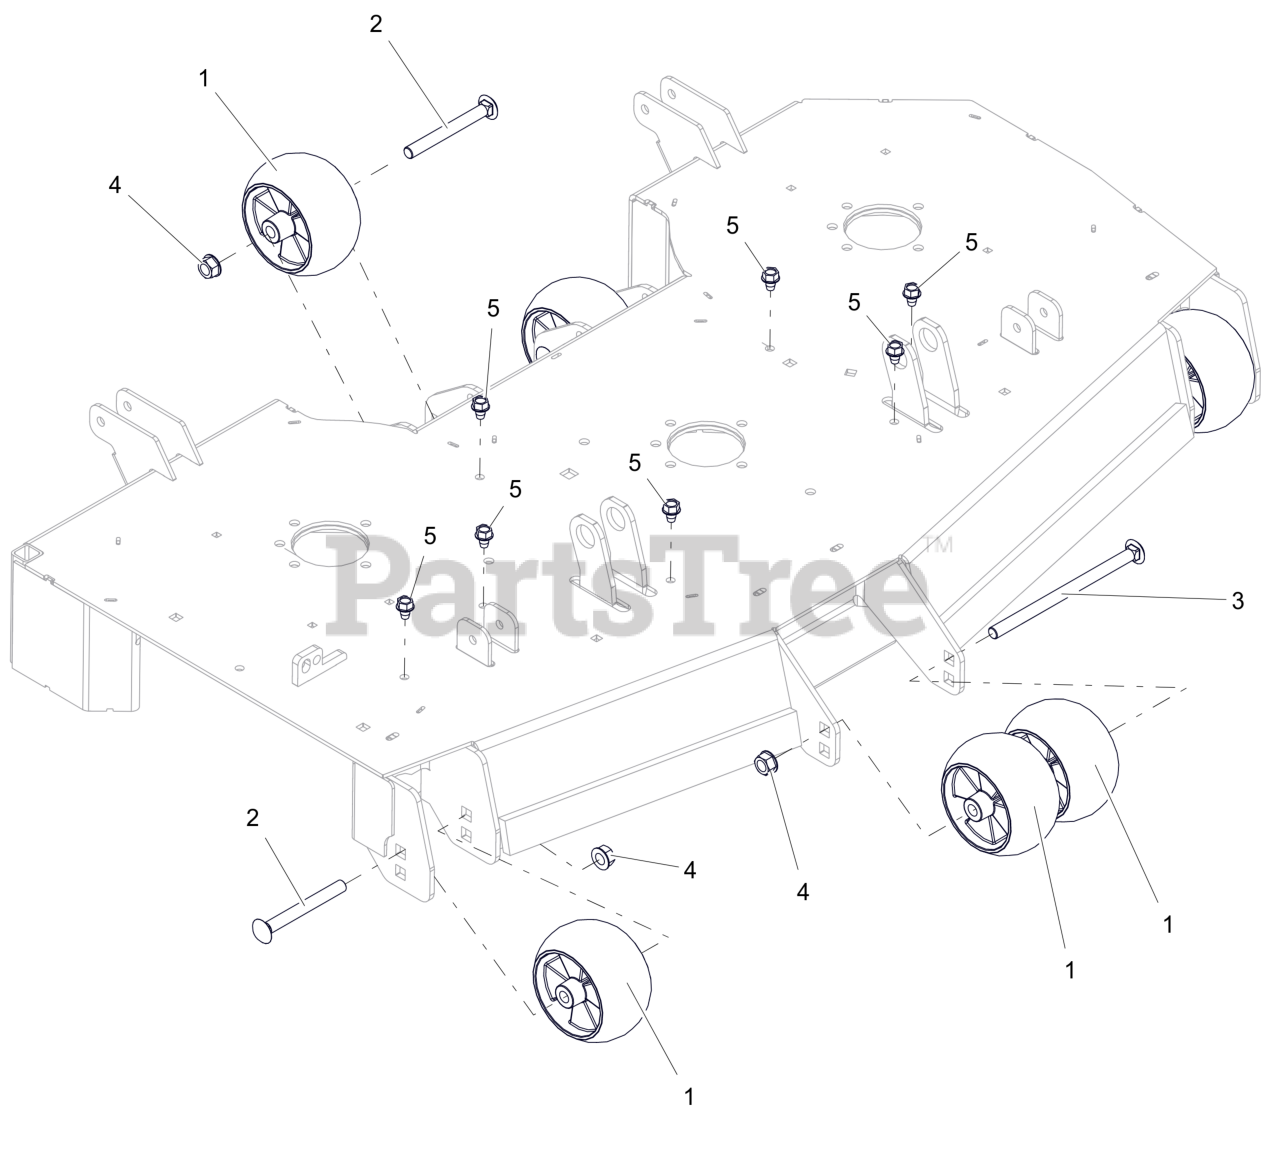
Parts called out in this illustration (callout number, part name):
1	WHEEL, ANTI SCALP - 5X3 CTR W/RIBS
2	BLT,RHNS .50-13X4.50 G5 ZCC NS
3	BLT,RHSN .50-13X8.00 G5 ZCC NS
4	NUT-LK-CTR-FLG .500-13 GG ZCC
5	SCR,TAP .375-16X.50 HWH TR ZCC
